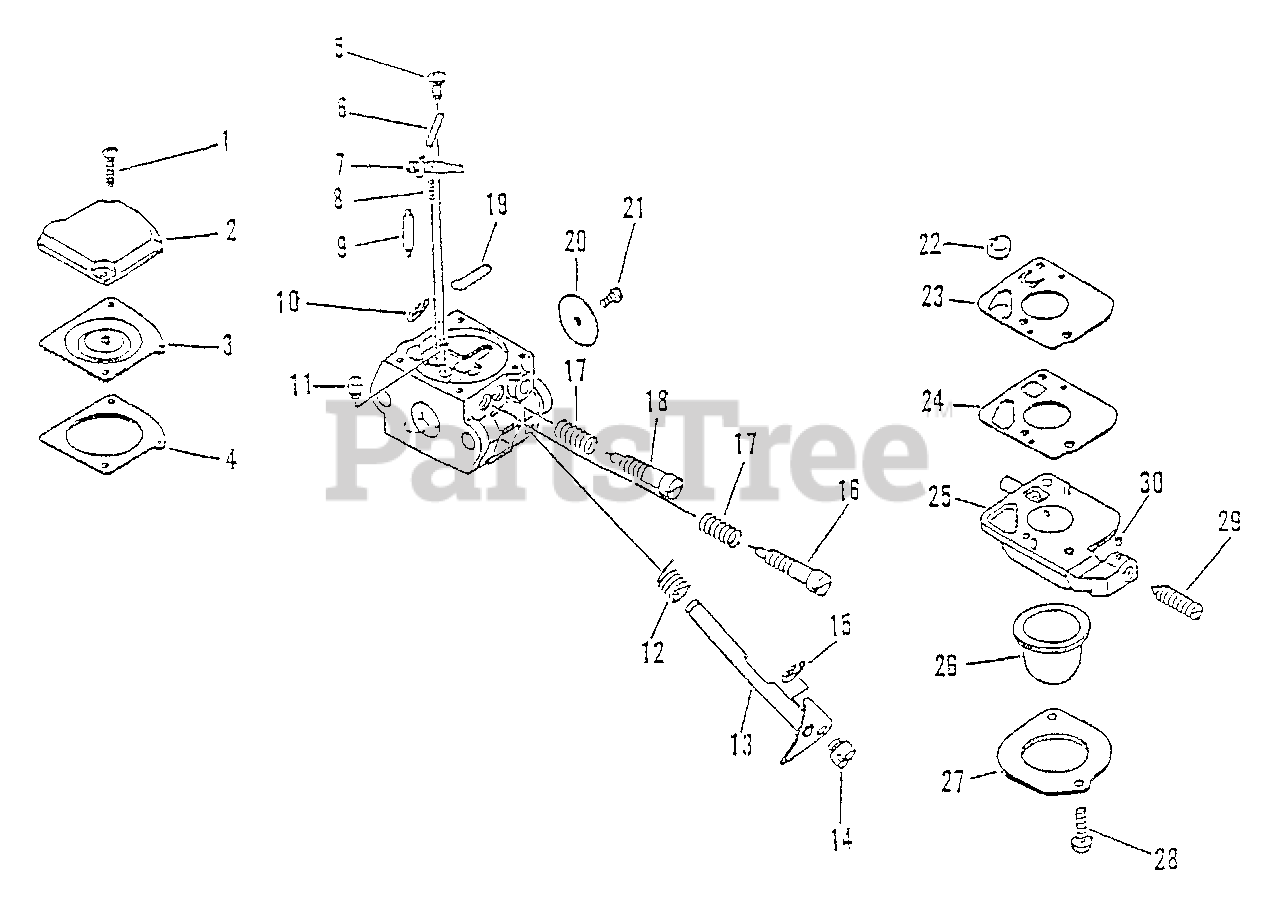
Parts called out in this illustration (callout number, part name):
2	COVER, METERING DIAPHRAGM
3	DIAPHRAGM
4	GASKET, METERING
5	SCREW
6	PIN
7	LEVER, METERING
8	SPRING
9	VALVE, NEEDLE
11	NOZZLE, CHECK VALVE
12	SPRING, THROTTLE RETURN
13	SHAFT, THROTTLE
16	NEEDLE, LOW SPEED
17	SPRING, NEEDLE
18	NEEDLE, HIGH SPEED
19	PLUG, WELCH
20	VALVE, THROTTLE
22	STRAINER
25	BODY ASSY, PURGE
26	BULB, PURGE
27	RETAINER
29	SCREW, IDLE ADJUST
30	PIECE, FRICTION
